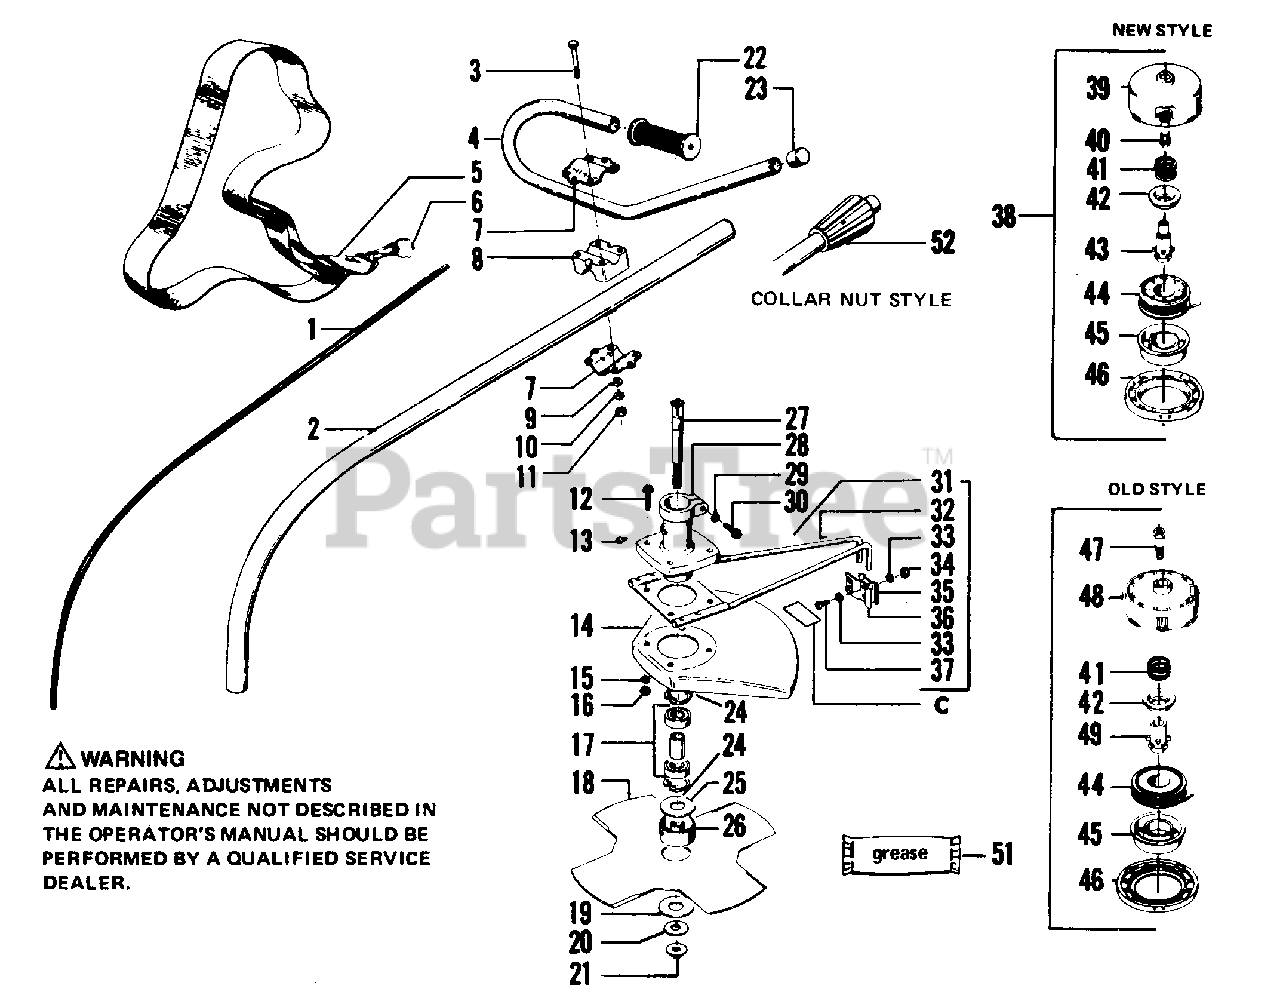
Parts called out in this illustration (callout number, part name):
1	Flexible Drive Shaft
2	Drive Shaft Housing
2	Collar Nut Style (Inc. 52)
2	Pinch Clamp Style
3	Bolt - #1/4 - 20 x 2" Hex
4	Barrier Handlebar
5	Shoulder Strap
6	"O" Ring - Shoulder Strap
7	Clamp - Handlebar
8	Block - Handlebar
9	Washer - 1/4" Flat
10	Washer - 1/4" Lock
11	Nut - #1/4 - 20" Hex
12	Screw - #1/4 - 20 x 1" Hex
13	Screw - #10 - 16 x 1/4 Self Tapping
14	Shield - Aluminum
15	Washer - 1/4" Flat
16	Nut - Deflector to Bearing Housing (1/4 - 20)
17	Bearings and Spacer Kit
18	Blade - 4 Tooth Weed
19	Washer - Flat
20	Washer - Bevel
21	Flange Nut
22	Grip - Handlebar
23	End Cap - Handlebar
24	Retaining Ring - Bearing
25	Washer - Dust Cup
26	Dust Cup
27	Shaft - Arbor
28	Bearing Housing Ass'y (Inc. 17 & 24-30)
29	Washer - 1/4" Int. Tooth
30	Screw - #1/4 - 20 x 1" Hex
31	Line Limiter Ass'y (Inc. 32 - 37)
32	Line Limiter Bracket
33	Washer
34	Nut - #10 - 24" Locking
35	Clamp - Line Limiter Front
36	Clamp - Line Limiter Rear (Includes Blade)
37	Screw - #10 - 24 x 3/8"
38	Cutting Head Ass'y - New Style (Inc. 39 - 46)
39	Hub w/Line Saver - New Style
40	Line Saver
41	Spring
42	Adaptor - Spring
43	Drive Gear - New Style
44	Spool With Line (.080" dia.)
45	Release Button
47	Bolt - Drive Adaptor - Old Style
48	Hub w/Line Saver - Old Style
49	Drive Gear - Old Style
51	Flex Shaft Lube
52	Collar Nut
